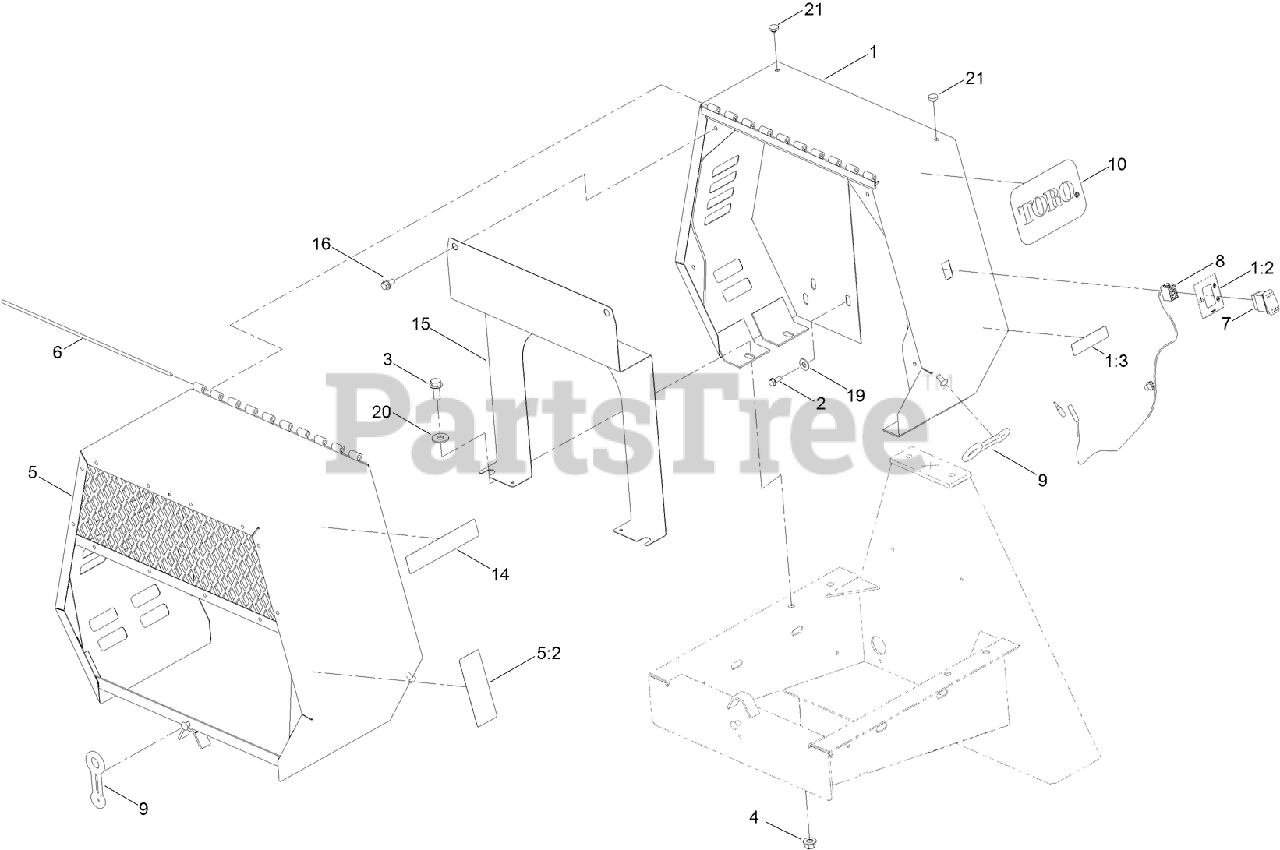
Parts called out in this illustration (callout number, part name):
1	STATIONARY COWL ASM
1:2	DECAL-STOP, ENGINE
1:3	DECAL-ARRESTER, SPARK
2	SCREW-THD ROLL, HWH
3	SCREW-HHF
4	NUT-LOCK
5	MOVABLE COWL ASM
5:2	DECAL-WARNING
7	SWITCH
8	HARNESS-WIRE, MIXER
9	LATCH-RUBBER
10	DECAL
15	PLATE-ENGINE
16	SCREW-HWH
19	WASHER-FLAT
20	WASHER-FLAT
21	BUMPER
